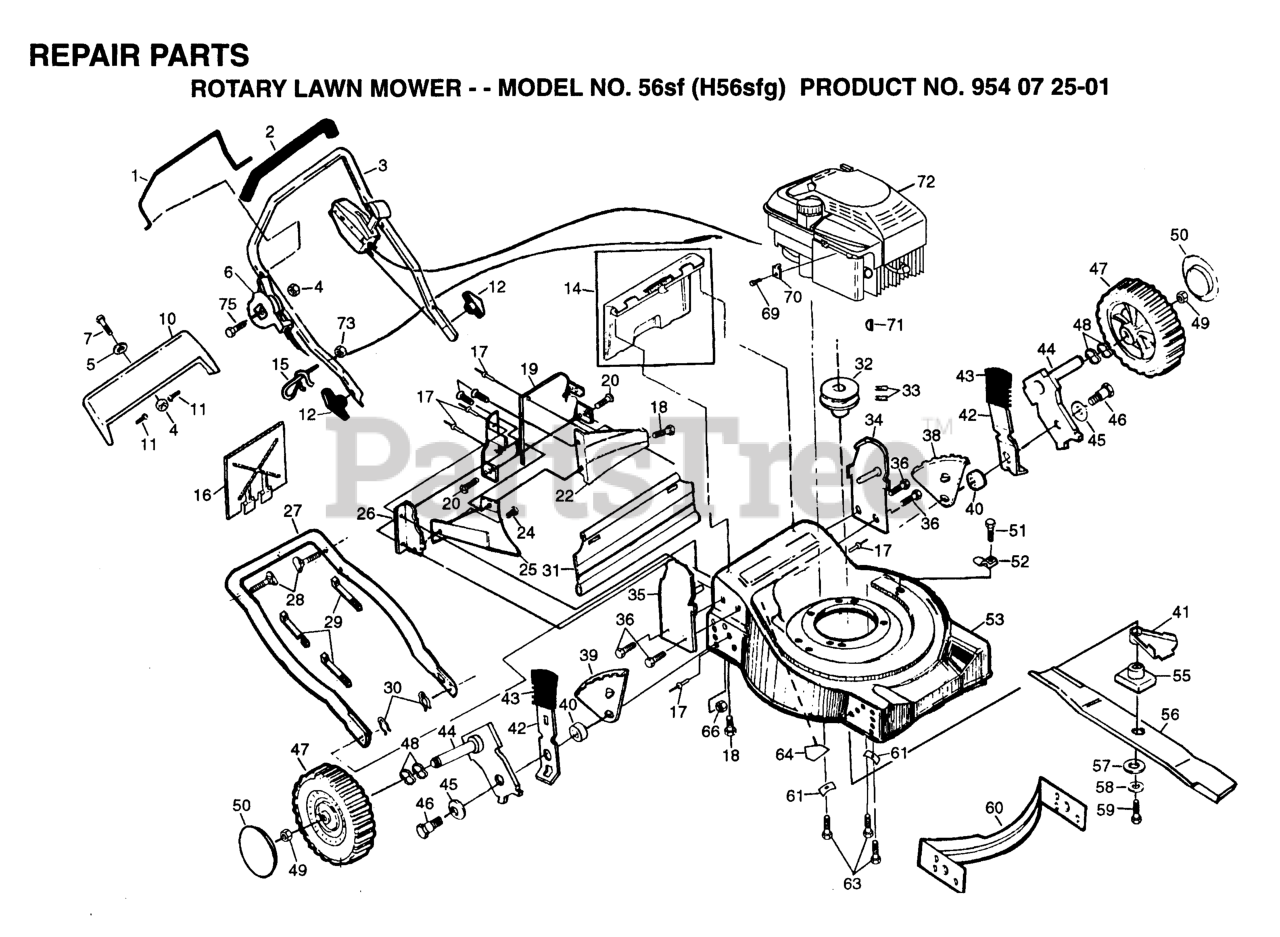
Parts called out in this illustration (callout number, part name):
1	CONTROL BAR
2	HANDLE GRIP
3	UPPER HANDLE
4	NUT
6	THROTTLE CONTROL
7	SCREW
10	TRIM PLATE
12	HANDLE KNOB
14	REAR DOOR ASSEMBLY
15	ROPE GUIDE
16	MULCHER PLATE
17	RIVET BLIND
19	BACK PLATE
20	HINGE SCREW
22	REAR BAFFLE
25	DISCHARGE BAFFLE
26	SIDE BAFFLE
27	HANDLE, LOWER PM
28	HANDLE BOLT
29	TIE GUIDE
30	HAIRPIN COTTER
31	REAR SKIRT
32	ENGINE.PULLEY.FWG
34	HANDLE BRACKET LH
35	HANDLE BRACKET RH
36	SCREW
38	WHEEL ADJ BRKT RF-LR
39	WHEEL ADJ BRKT RR-LF
40	SPACER PM
41	DEBRIS SHIELD
42	SELECTOR SPRING
43	SELECTOR KNOB
44	AXLE ARM ASSY FT
45	WASHER.BELLEVILLE (3 2 LB)
46	BOLT
47	WHL & TIRE ASSEMBLY
48	WAVE WASHER
49	HEX FLANGE LOCKNT
51	TAPPING SCREW
52	GUIDE CLIP PM
53	HOUSING KIT
55	BLADE ADAPTOR
57	WASHER,HARDEN
58	LOCKWASHER
59	SCREW, HEX HD 3/8-24 X 1-3/8
60	FRONT BAFFLE
61	WASHER.ENGINE.BZP
62	RETAINER RING DEBRIS SHIELD
63	BOLT
64	DECAL HYT
66	LOCKNUT PM
69	SCREW.HEX.HEAD.WASHER.10-16
70	WASHER
71	HI PRO KEY PM WSL
73	NUT
75	SCREW 1/4-20X1.75
